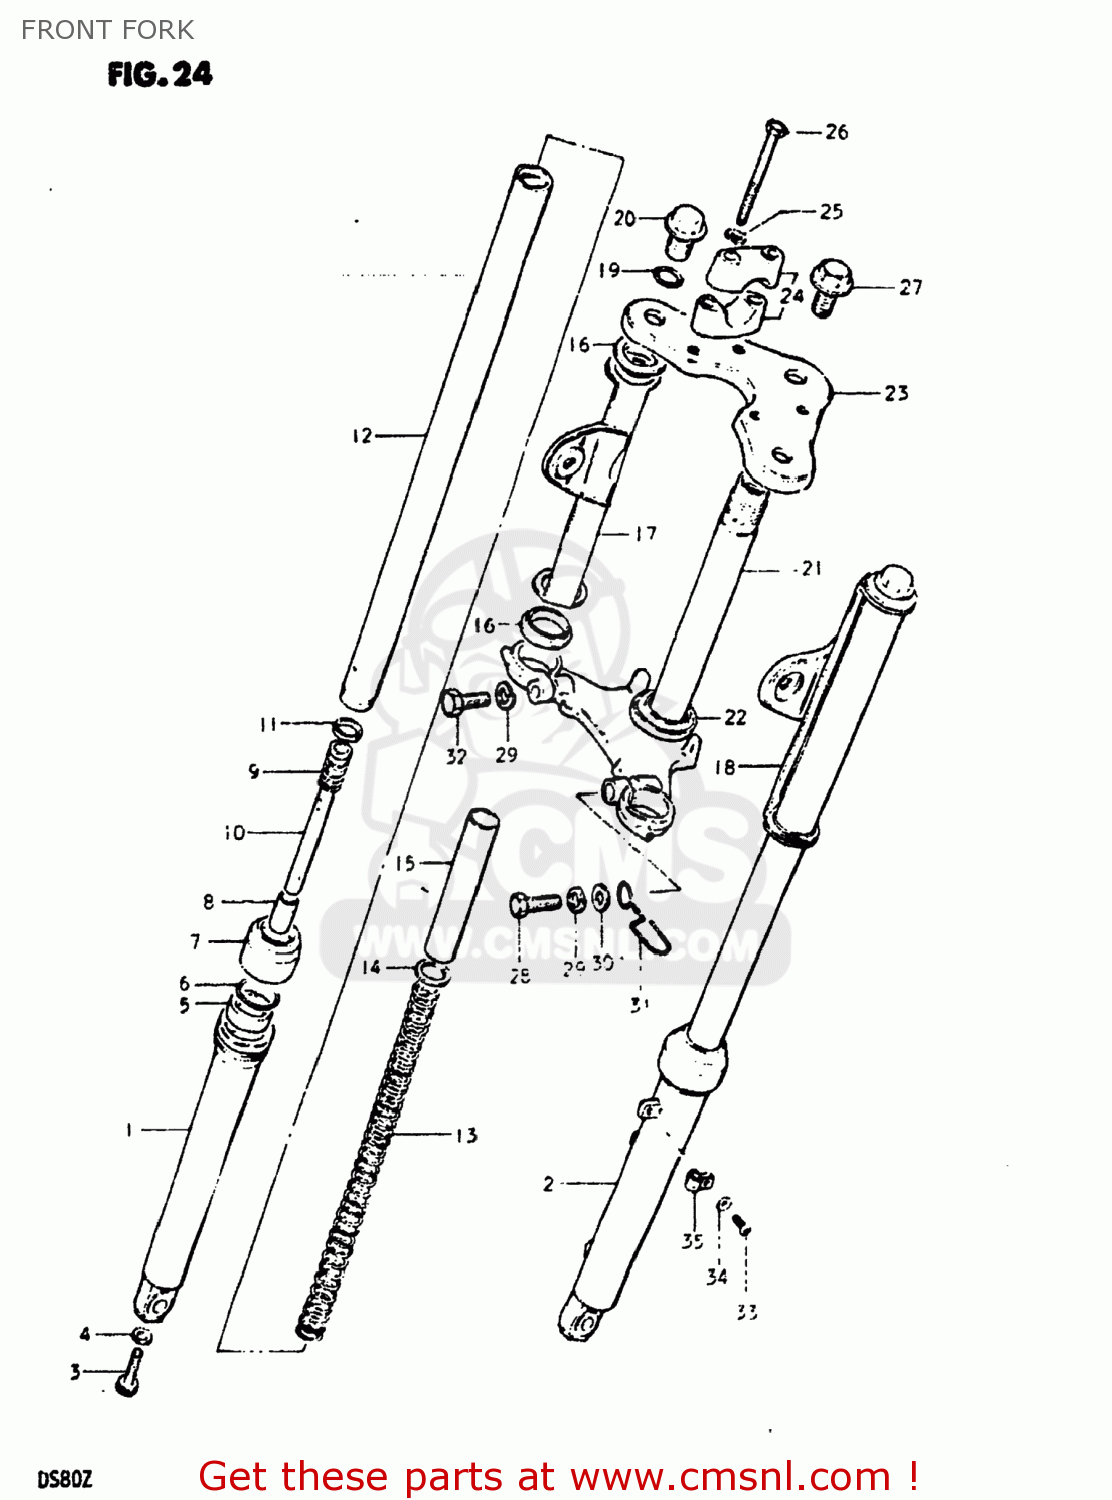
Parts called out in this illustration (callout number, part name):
1	TUBE,OUTER,RIGHT
2	TUBE,OUTER,LEFT
3	BOLT(8X27)
4	GASKET (NAS)
5	OIL SEAL,FRONT FORK
6	CIRCLIP,FORK OIL SEAL
7	DUST SEAL
8	PIECE,OIL LOCK
9	SPRING,REBOUND
10	CYLINDER,FRONT FORK
11	RING,PISTON
12	TUBE,INNER
13	SPRING
14	JOINT,SPRING
15	SPACER,SPRING
16	CUSHION
17	BRACKET,HEADLAMP,RIGHT
18	BRACKET,HEADLAMP,LEFT
19	O-RING,FORK INNER TUBE
20	CAP
21	STEM,STEERING
22	RACE,STEERING OUTER LWR
23	HEAD,STEERING STEM
24	HOLDER,HANDLE UPR
25	LOCK WASHER
26	BOLT 8X55
27	BOLT
28	BOLT,M10X1.25X
29	LOCK WASHER
30	WASHER
31	CLAMP,METER CABLE
32	BOLT 10X30
33	SCREW
34	LOCK WASHER
35	CLIP,CABLE
